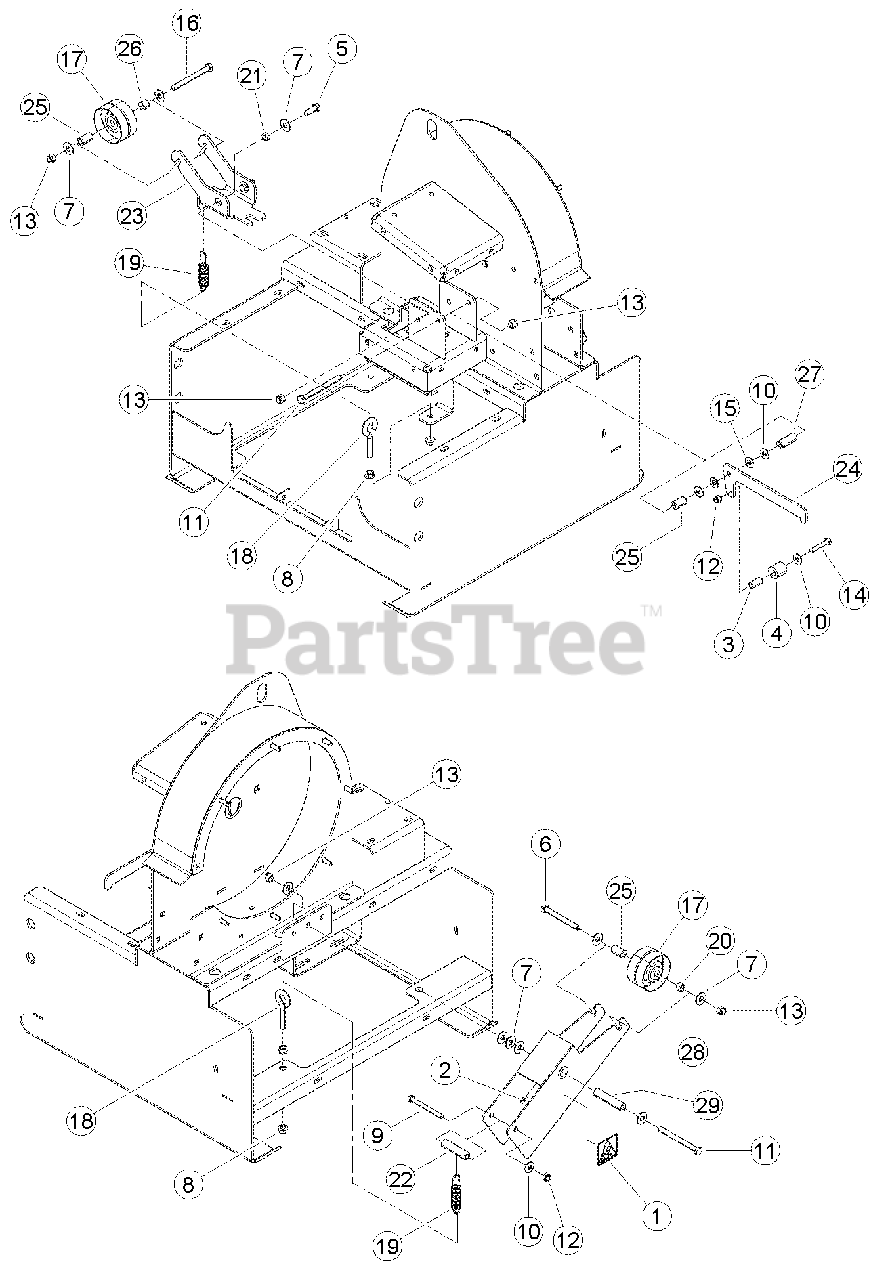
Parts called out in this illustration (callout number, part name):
1	DECAL, SHIELD DANGER ISO
2	FITTING, 1/4 SELF-TAP GREASE
3	SPACER, 0.5 X 1.00
4	ROLLER, 0.5 X 1.00 X 1.00 NYLON
5	BOLT, 3/8 X 1 HEX HD GR5 ZP
6	BOLT, 3/8 X 3-1/2 HEX HD GR5 ZP
7	WASHER, 3/8 FLAT ZP
8	NUT, 3/8 SERR FLANGE NC ZP
9	BOLT, 5/16 X 3-1/4 HEX HD GR5
10	WASHER, 5/16 FLAT ZP
11	BOLT, 3/8 X 4 HEX HD GR5 NC ZP
12	NUT, 5/16 NE NYLOCK ZP
13	NUT, 3/8 NE NYLOCK ZP
14	BOLT, 5/16-18 X 1-3/4 HEX HD GR5 ZP
15	WASHER,3/8 NYLON .062 TH FLAT
16	BOLT, 3/8 X 3-3/4 HEX HD GR5 ZP
17	PULLEY, 3-1/4 FLAT IDLER
18	EYE BOLT G-2, 3/8 X 2 ZP
19	SPRING, 3/4"OD EXTENSION
20	BUSHING
21	SPACER IDLER PIVOT
22	SPACER, .63 X 2.44
23	BRACKET, IDLER
24	LEVER, ENGAGEMENT
25	SPACER, .63 X 1.035
26	SPACER,.63 X .515
27	SPACER, .63 X 1.560
28	WELDMENT, IDLER
29	SPACER, .63 X 2.880
